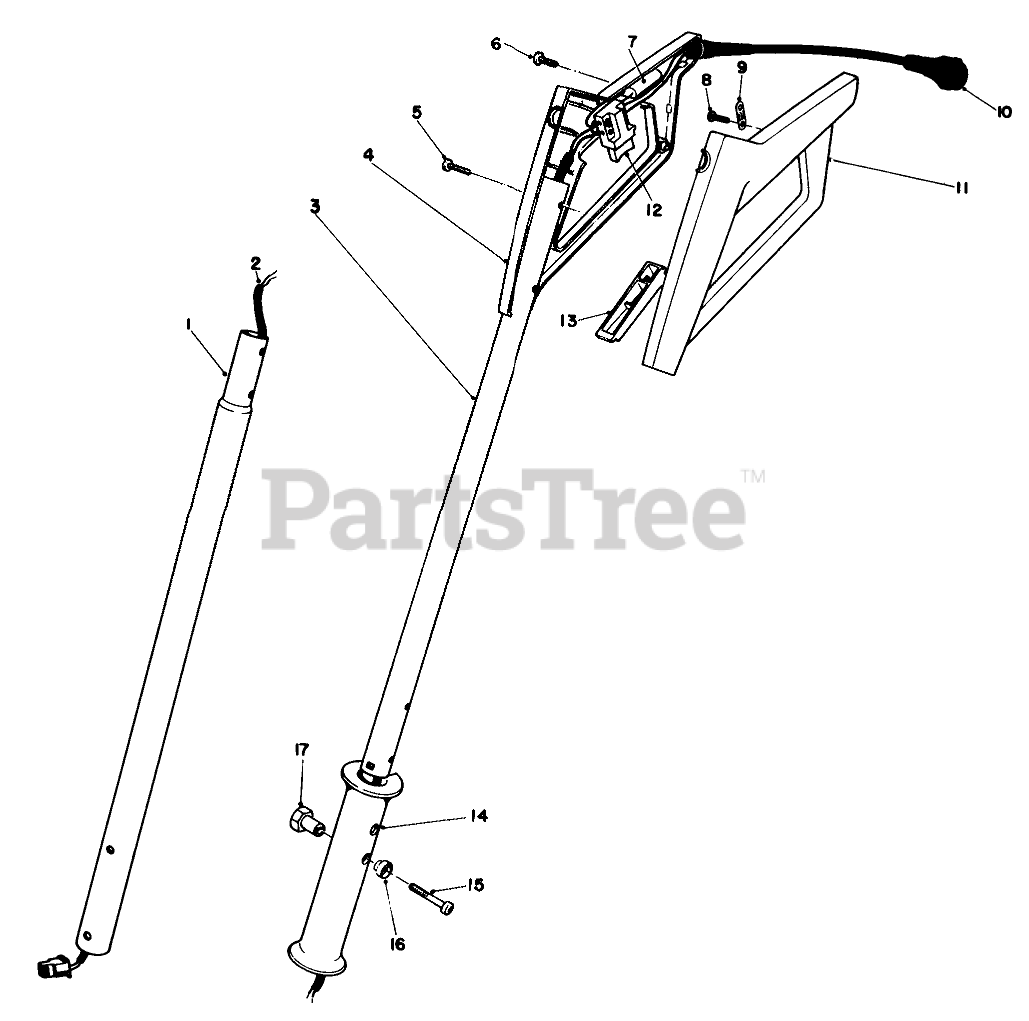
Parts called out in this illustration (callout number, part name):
1	LOWER TUBE, P. SHOVEL
2	Wire Harness
3	Tube-Upper Handle
4	Grip-Control R.H.
5	Screw
6	SCREW-PPH
7	CAPACITOR
8	Screw, Pan Head
9	Clamp-Power Cord
10	Power Cord-Upper Wiring Harness
11	LH CONTROL GRIP
12	Switch
13	Switch Bar
14	Grip-Handle
15	SPEC PAN HD SCREW
16	Bushing-Screw
17	SPECIAL HEX NUT
